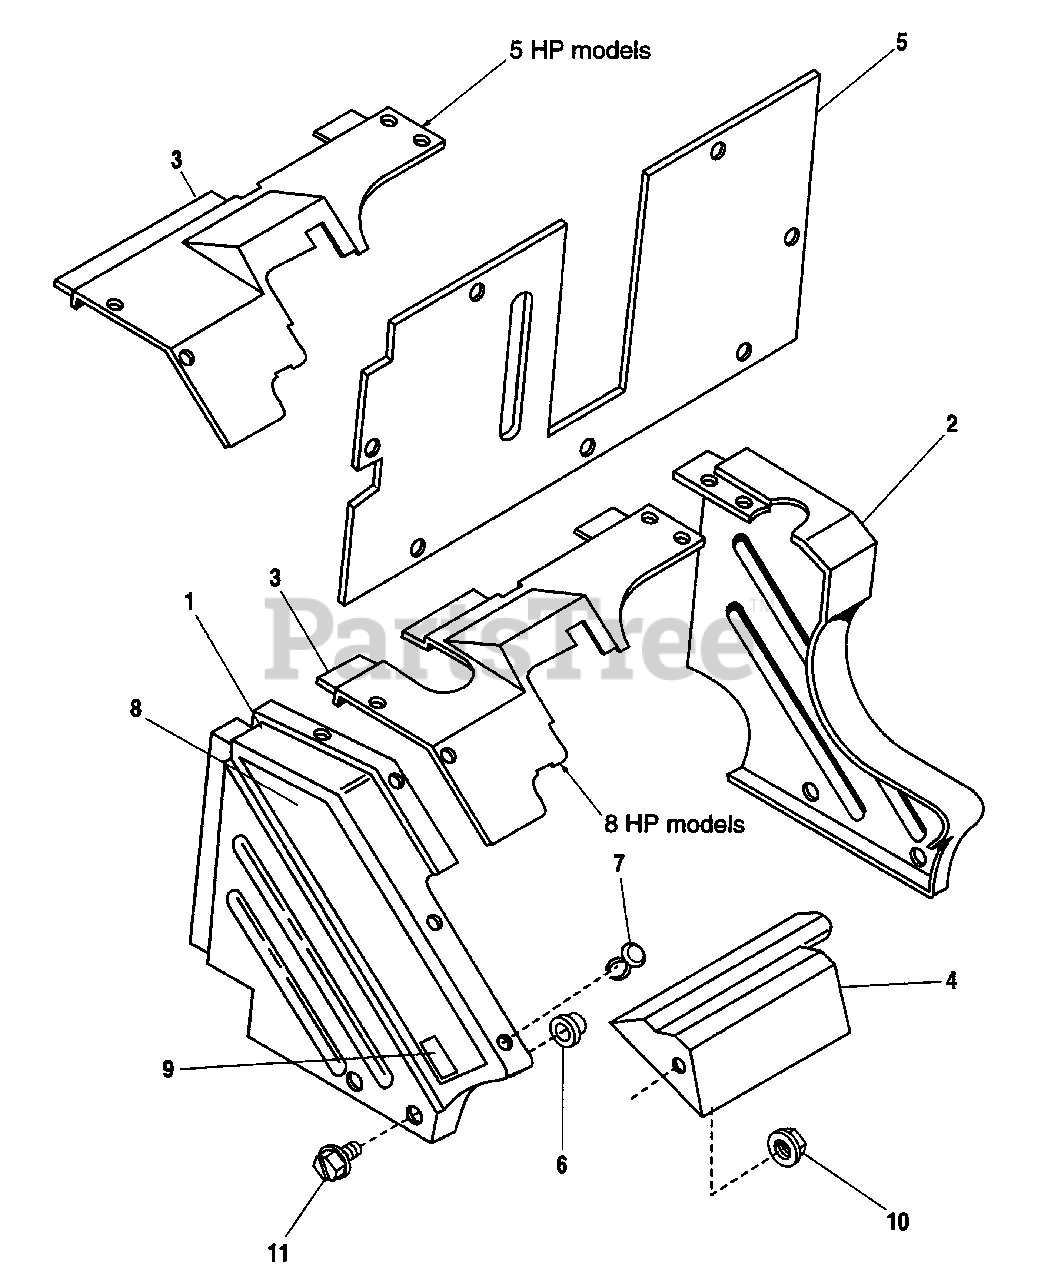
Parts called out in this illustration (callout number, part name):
2	COVER, LH
3	COVER, Top (8 HP models)
3	COVER, Top (5 HP models)
4	COVER, Bottom
5	COVER, Rear
6	GROMMET, Front Mount
7	FASTENER, Panel
8	DECAL (Simplicity 5/25)
8	DECAL (Baker 5/25)
8	DECAL (Simplicity 8/25)
8	DECAL (Baker 8/25)
9	DECAL, Electric Start
10	NUT, Hex, Flange Lock, 5/16-18
11	SCREW, Plastite, #10-14 x 5/8
